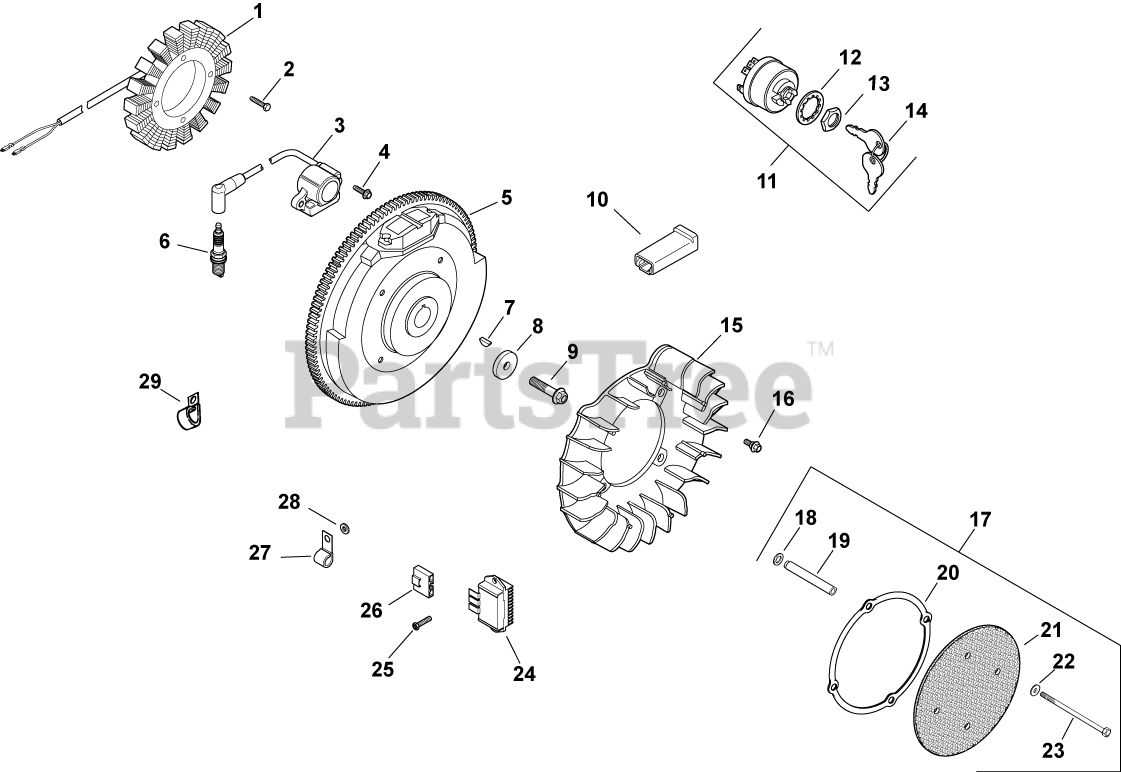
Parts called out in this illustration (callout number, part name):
1	KIT, 15 / 20 AMP STATOR
2	SCREW, M5X0.8X25 - (#25086402S)
3	KIT, MODULE IGNTN (CDI FIXED)
4	SCREW, FLG THD FRM M5X.8X20-(#25086399S)
6	PLUG, SPARK (STD)
7	KEY, 3/16" X 5/8"
8	WASHER, FLAT 13/32"
9	SCREW, FLG M10X1.5X85 USE 62 086 08-S
10	CONNECTOR (1 CONTACT)
11	SWITCH ASSY, KEY (KM)-USE 25 099 32-S
12	WASHER, INTERNAL TOOTH
13	NUT, KEY SWITCH
14	KEY, SET -USE 48 340 01-S
15	FAN USE 24 755 253-S
16	SCREW, SKT SET #10-24X1/4"
17	KIT, CHOPPER SCREEN
18	WASHER, SPRING 10 MM
20	RING, SUPPORT USE 25 141 08-S
21	SCREEN, GRASS-USE 24 162 39-S
22	WASHER, FLAT 1/4" (O.D. 5/8")
23	SCREW, CAP M6X1.0X99.5
24	REG/RECT-15 AMP (KM)-USE 41 403 10-S
25	SCREW, HEX FLANGE HI-LO
26	CONNECTOR, BODY (KM)-USE 25 155 41-S
27	CLIP, CABLE
28	WASHER, FLAT 1/4" (O.D. 1/2")
29	CLIP, TUBE & WIRING (KM)
